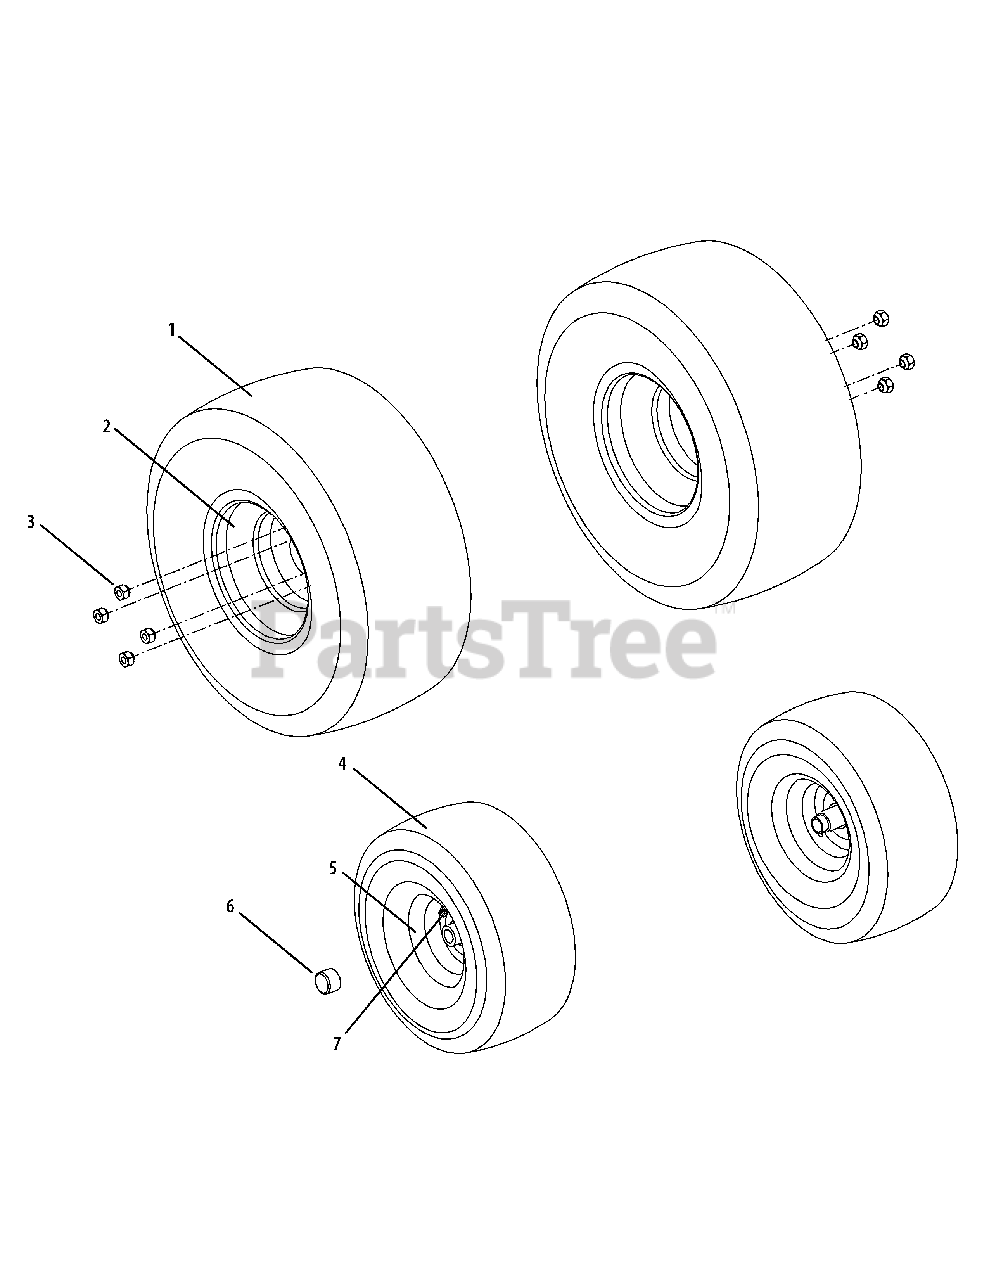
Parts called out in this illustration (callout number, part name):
1	Wheel Ass’y, Complete
1	Tire, 20 x 10 x 8 Square Shoulder
2	Rim Assembly, 8.0 x 6.19
3	Lug Nut, 7/16-14
4	Wheel Ass’y, Complete, 15 x 6 x 6
4	Tire, 15 x 6 x 6 Square Shoulder
5	Rim Assembly, 6 x 4.5
7	Valve, Tubeless Air
